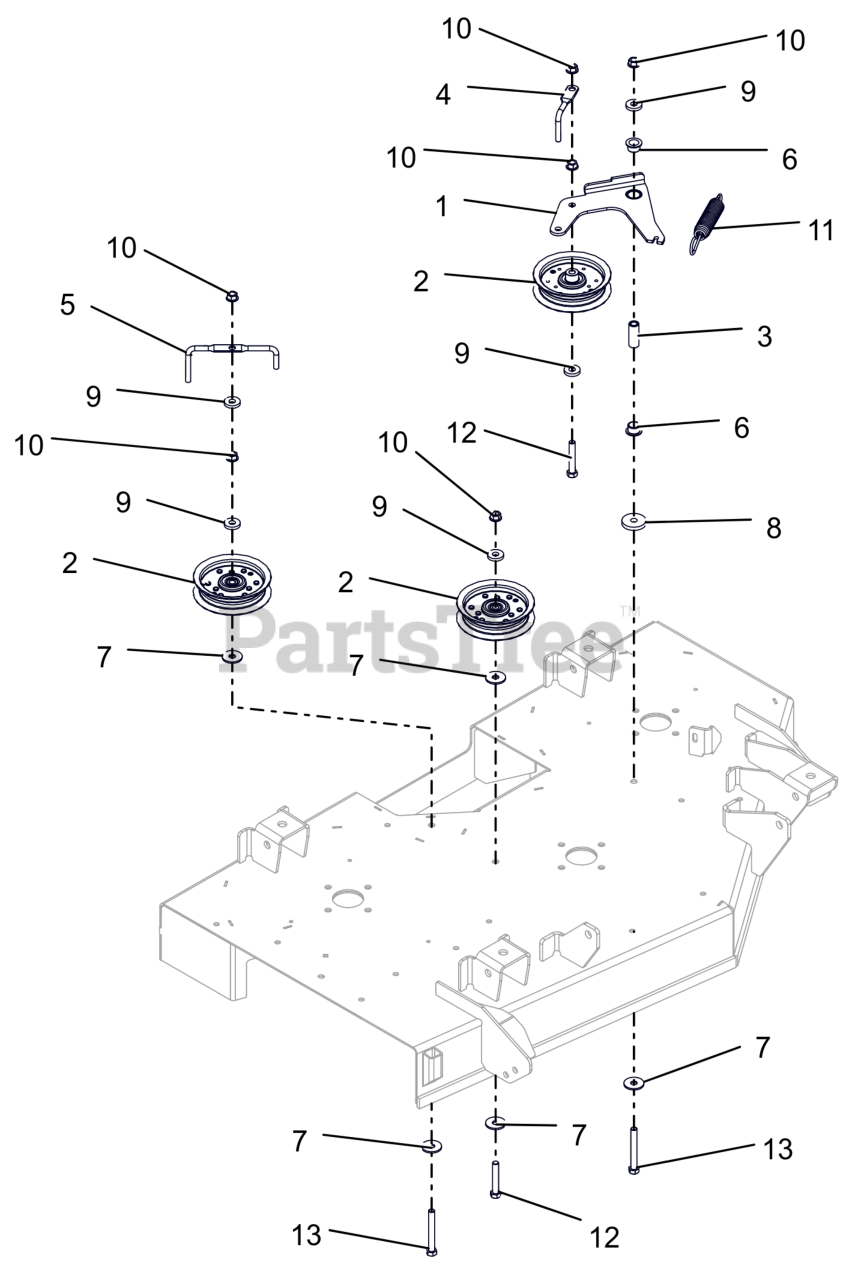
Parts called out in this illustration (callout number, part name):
1	WLDMT, IDLER ARM-42"
2	ASM, IDLER 4"
3	SPACER, .375IDX.625ODX1.66 PM
4	WIREFORM, BELT FINGER
5	WIREFORM, BELT FINGER
6	BSHG-FLG, .625X.750X.500X1.00
7	WSHR FL STL .406X1.25X.10ZC120
8	WSHR, FLT .406X1.50X.245 ZCC
9	WSHR, FLT .406X1.00X.188 ZCC
10	NUT-LK-CTR-FLG .375-16 GF ZCC
11	SG-TENS .135X.98X6.0 WLD 62
12	BLT,HEX .38-16X2.25 G5 ZCC
13	BLT, HEX .38-16X3.00F G5 ZCC
